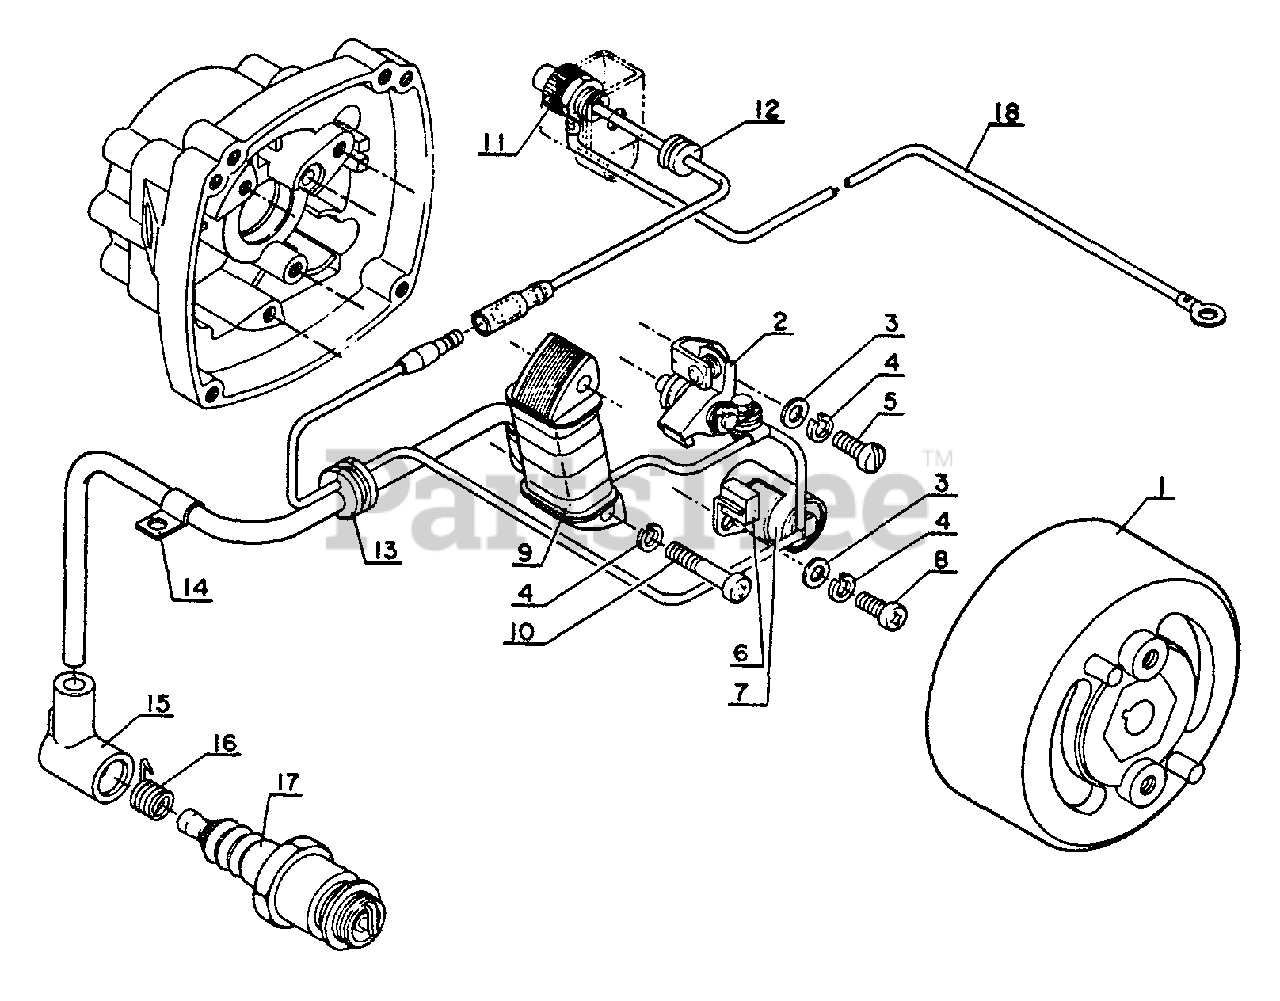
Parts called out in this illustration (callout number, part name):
1	FLYWHEEL
2	CONTACT POINT SET
3	WASHER - 4
4	LOCKWASHER - 4
5	SCREW - 4X8
6	PAD, OIL
7	CONDENSER
8	SCREW - 4X8
9	COIL, IGNITION
10	SCREW - 4X25
11	BUTTON, STOP
12	GROMMET
14	CLAMP
15	CAP, SPARK PLUG
16	TERMINAL, SPARK PLUG CAP
17	SPARK PLUG -- BM-6A
18	LEAD - GROUND
